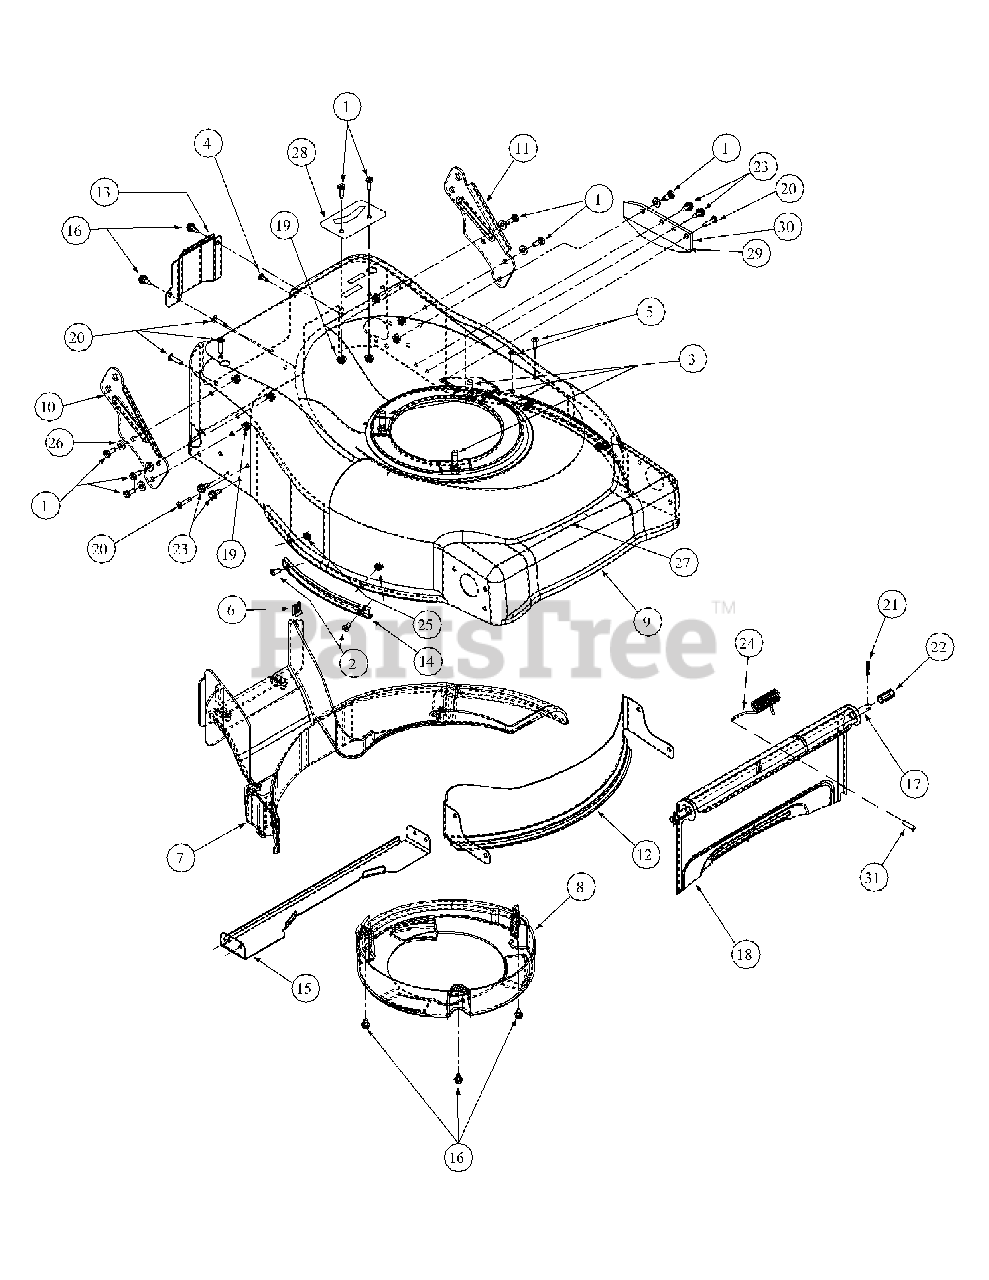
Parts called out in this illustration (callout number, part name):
1	HHCS, 1/4-20, .620, GR5, Standard
2	Screw Button HD, 1/4-20 x .5
3	Screw, TTSems, 3/8-16, 1.250, HXLWS
4	Screw, B, 10-16, 0.500, TRUSTRX1
5	Screw, HL, 12-16:0.750, TRUSTRX1
6	U-Nut, 10-16
7	Baffle, RR, 21" Commercial
8	Cover, 21" Commercial
9	Deck, 21" Commercial
10	Handle Bracket, RH Commercial
11	Handle Bracket, LH Commercial
12	Front Baffle Commercial 10.81 R
13	Transmission Cover Plate
14	Deck Guard Side Flange
15	Baffle Support Bracket
16	Screw, TT, 1/4-20, 0.375, Hex Indicator Washer
17	Chute Door Pivot Rod, .375 Dia
18	Door, Grassbag, 21" RB
19	Nut, 1/4-20, Hex Flange, Lock Group F
20	Screw, HL, 12-16, 1.000, TRUSTRXI
21	Cotter Pin, INT .072 x 1.12 LG
22	Spacer, .375 x .50 x 1.02 LG
23	Screw, AB, 1/4-14, 0.625, Hex Indicator Washer
24	Torsion Spring, LH 0.120 x 15C
25	Lock Hex Nut, 1/4-20
26	Flat Washer, 1/4 x .630 x x .0515
27	Label 21" Commercial
28	Shift Selector Bracket
29	Rubber Flap Deflector
30	Flap Deflector Bracket
31	Vinyl Spring Cap
